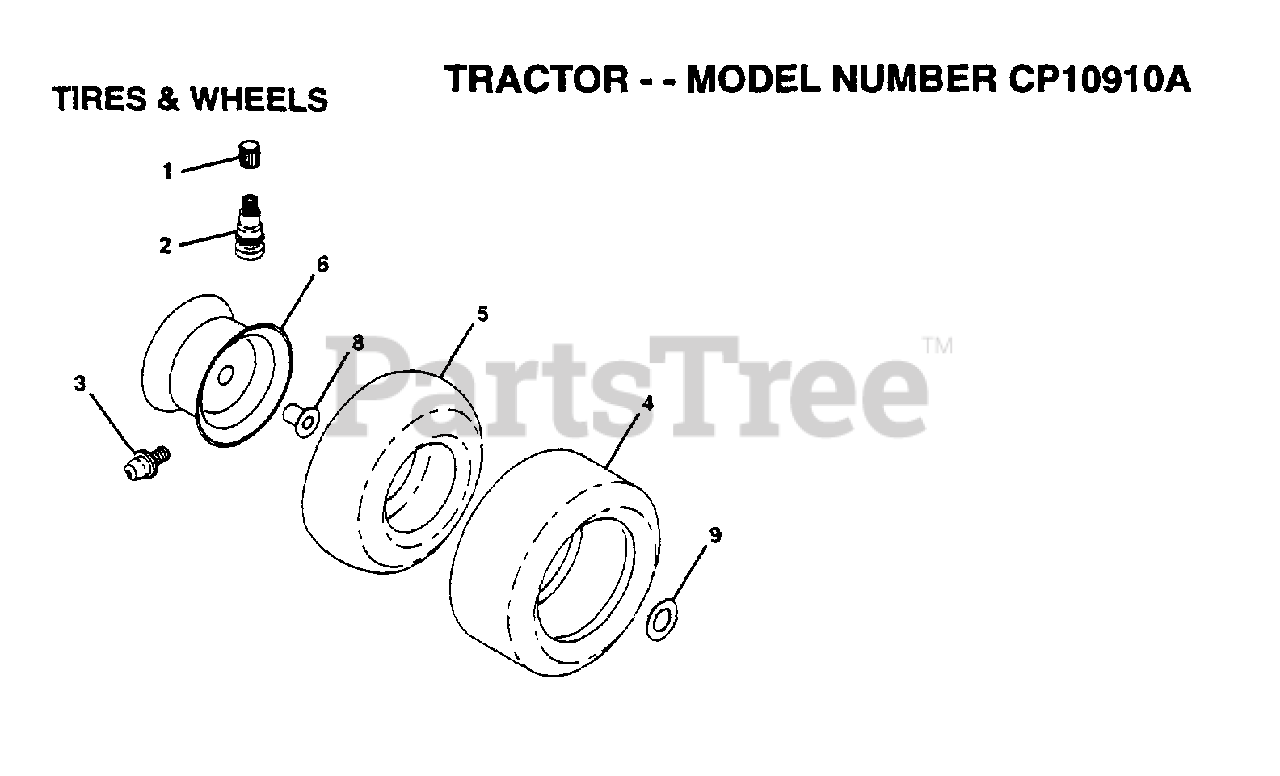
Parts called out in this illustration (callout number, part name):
1	VALVE CAP
2	VALVE STEM LT
3	FITTING LT
5	TUBE.5.3/4.5/6
6	"RIM FRONT 6"""
8	"FLANGE, BEARING"
9	WASHER
